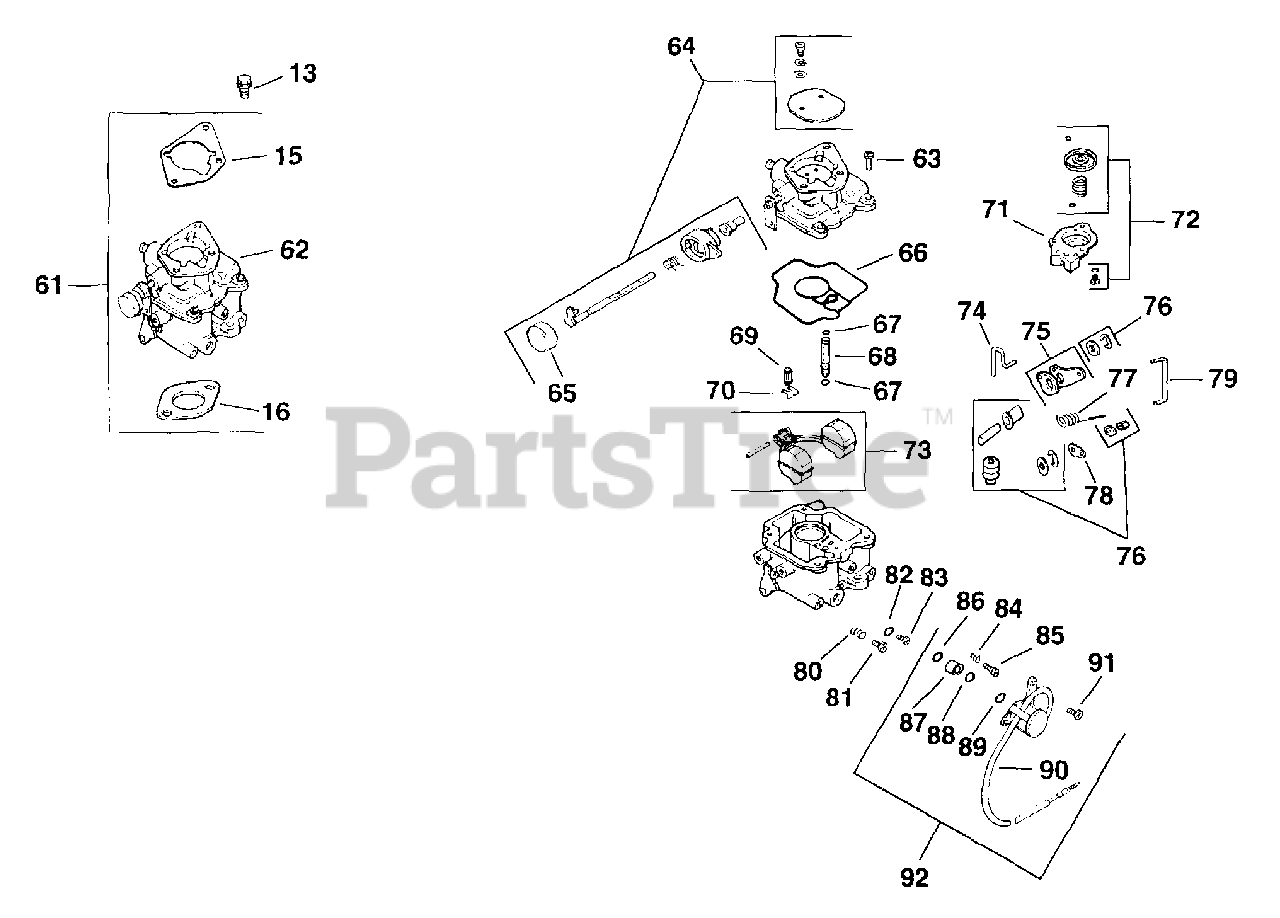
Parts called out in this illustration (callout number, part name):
13	SCREW - USE M-651030
15	GASKET, AIR CLEANER BASE
16	GASKET, CARBURETOR
61	CARBURETOR - USE 24 853 34
61	KIT, CARBURETOR W/GASKET KSF
62	Carburetor assembly
63	SCREW, CARBURETOR BODY
64	KIT, REPAIR CHOKE
65	CAP, CHOKE LEVER
66	GASKET, CARBURETOR BODY
67	O-RING, SLOW JET
68	JET, SLOW - DISCONTINUED
69	VALVE, INLET NEEDLE
70	CLIP, INLET NEEDLE VALVE
71	HOUSING, PUMP
72	KIT, REPAIR ACC PUMP
73	KIT, REPAIR FLOAT
74	LINKAGE, ROD
75	LEVER, LINK
76	KIT, REPAIR-ACC PUMP SEAL
78	LEVER, LINK
79	LINKAGE, ROD
80	SPRING, IDLE SPEED ADJ SCREW
81	SCREW, IDLE
82	O-RING, MAIN JET SCREW
83	JET, MAIN
84	SPRING, IDLE NEEDLE
85	NEEDLE, IDLE
86	O-RING, SOLENOID
87	SEAT, SOLENOID
88	O-RING, SOLENOID
89	O-RING, SOLENOID
90	SOLENOID ASSEMBLY
91	SCREW, SOLENOID
92	KIT, SOLENOID
